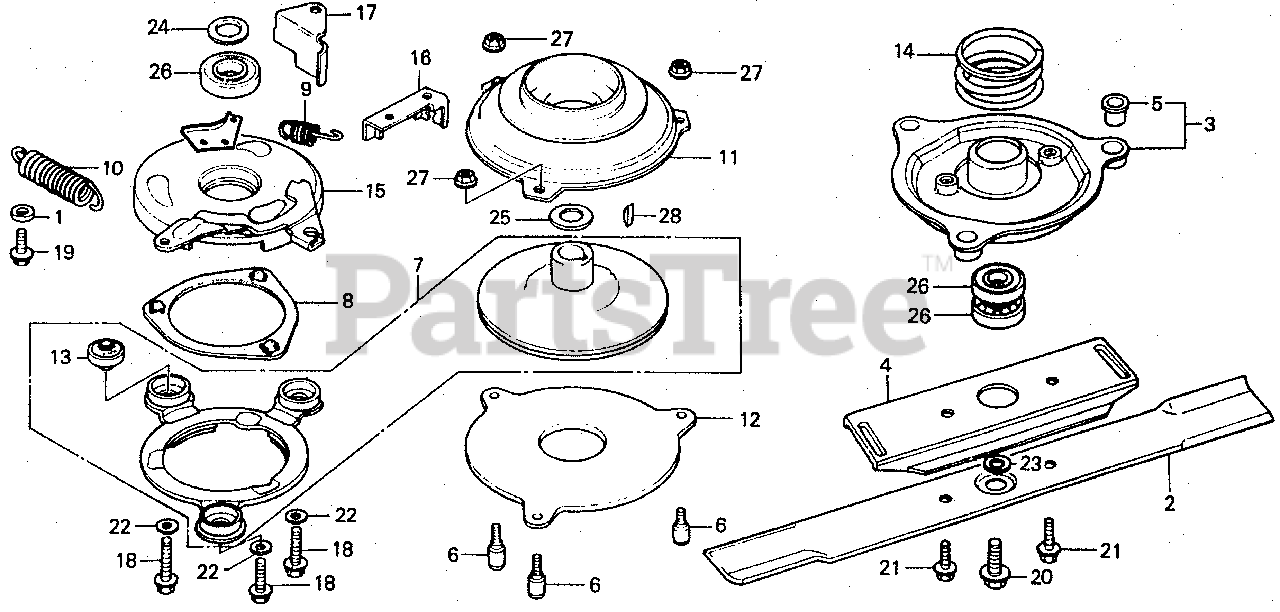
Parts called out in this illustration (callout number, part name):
1	COLLAR, FAN
2	BLADE, ROTARY
3	HOLDER ASSY., BLADE
4	HOLDER, BLADE
5	BUSH, BLADE HOLDER
6	PIN, DRIVE
7	DISK SET, BRAKE & CLUTCH
8	RETAINER, BALL
10	SPRING, ROTO-STOP CLUTCH RETURN
11	PULLEY, DRIVE
12	DISK, DRIVEN
13	RUBBER, CLUTCH
14	SPRING, CLUTCH (NOT AVAILABLE)
15	PLATE, BALL CONTROL (NOT AVAILABLE)
16	PLATE, CABLE HOOK (NOT AVAILABLE)
17	PLATE, BELT GUARD (NOT AVAILABLE)
18	BOLT, FLANGE (6X25) (CT200)
19	BOLT, FLANGE (6X16) (CT200)
20	BOLT, FLANGE UNF (3/8-24)
21	BOLT, HEX. (10X25)
22	WASHER (6MM)
23	WASHER (10MM)
24	WASHER, THRUST (22X32X3)
24	WASHER, THRUST
25	WASHER, THRUST (22X32X0.5)
26	BEARING, RADIAL BALL (60/22)
27	NUT, FLANGE (8MM)
28	KEY, WOODRUFF (16X15)
